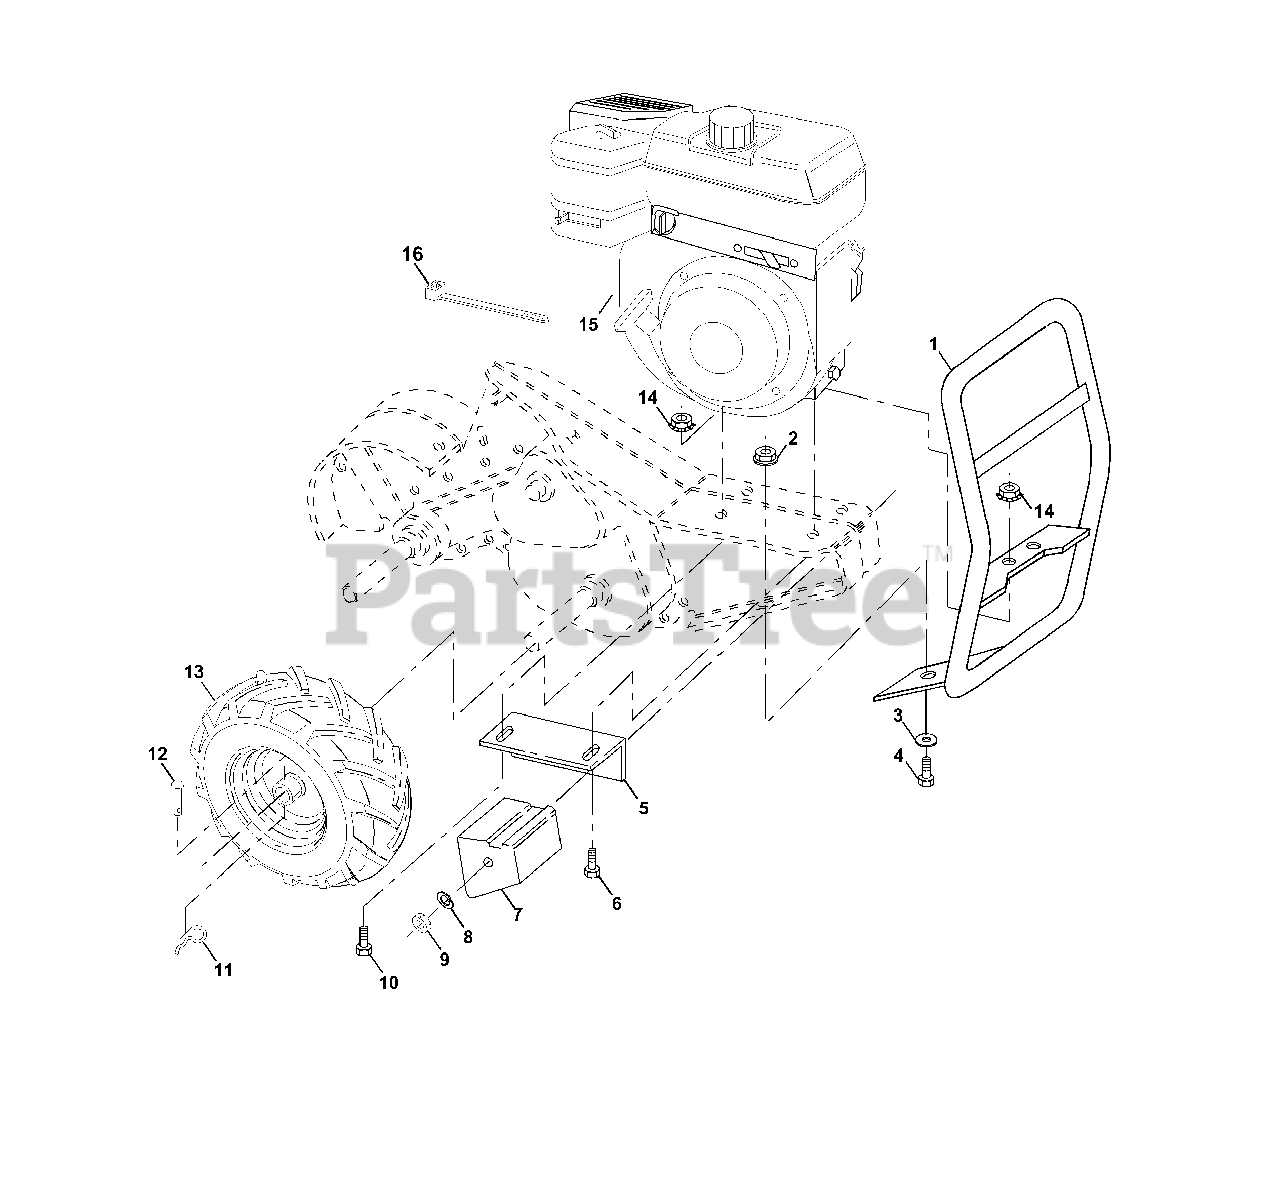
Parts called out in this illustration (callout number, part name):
1	Bumper
2	Locknut, Hex, Flange 5/16-18
3	Washer 11/32 x 11/16 x 16 Ga.
4	Bolt, Hex 5/16-18 x 3/4
5	Bracket, Reinforcement
6	Bolt, Hex 5/16-18 x 2
7	Counter Weight, R.H.
8	Washer, Lock 3/8
9	Nut, Hex 3/8-16
10	Bolt, Hex 5/16-18 x 1-1/2
11	Clip, Hairpin
12	Rivet, Drilled
13	Tire
13	Rim
13	Tire Valve
14	Nut, Keps 5/16-18
16	Tie, Cable
